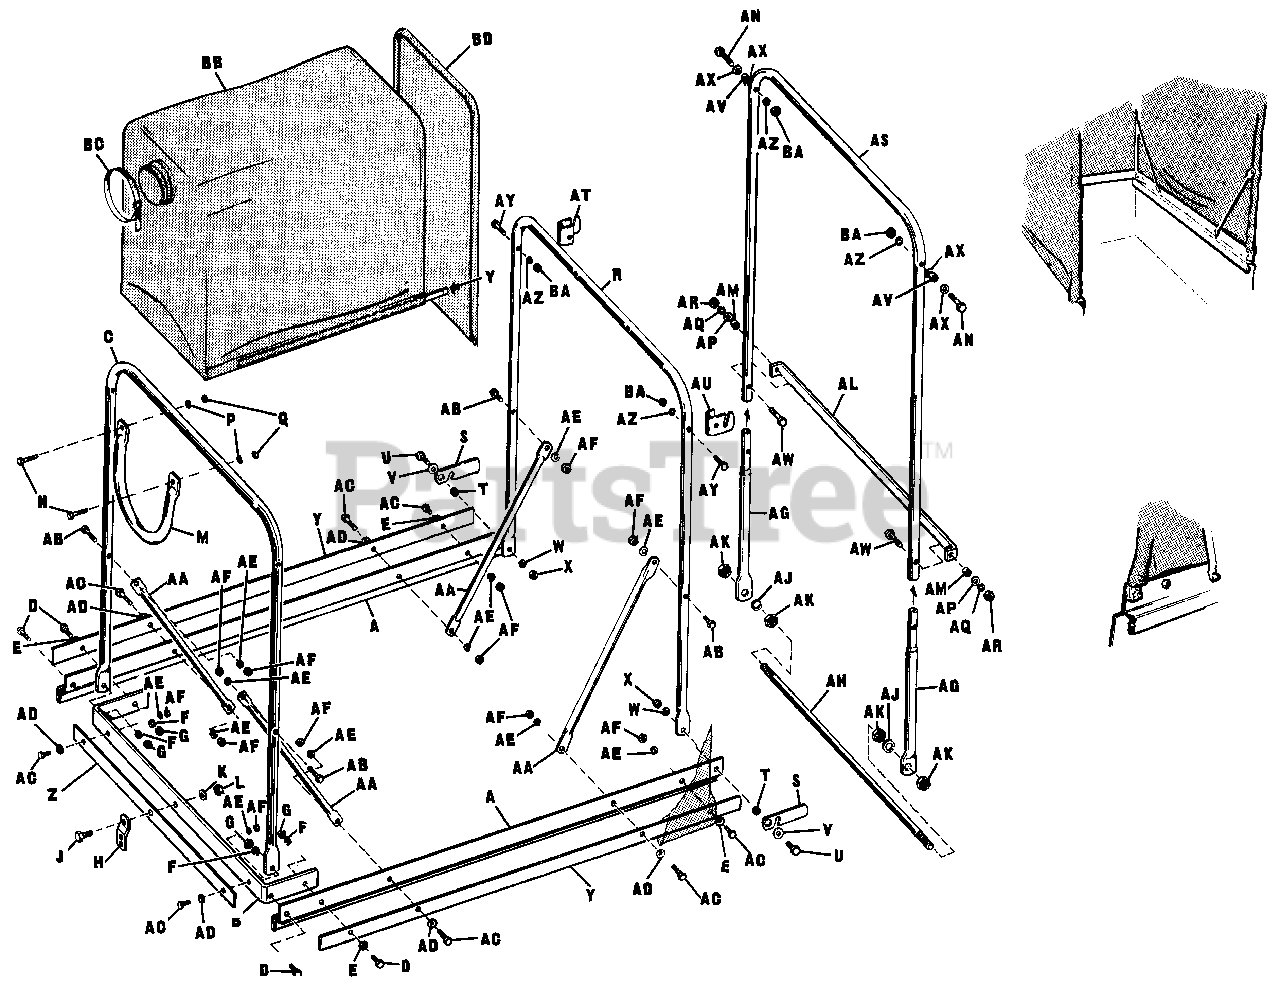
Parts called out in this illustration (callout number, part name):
A	"Z" Bar, Side
B	Front Bar
C	Front and Rear Upright
D	Hex Capscrew, 5/16"-18 x 1" lg.
E	Plain Washer, 5/16"
F	Lock Washer, 5/16"
G	Hex Nut, Full, 5/16"-18
J	Hex Capscrew, 3/8"-16 x 1" lg.
K	Plain Washer, 3/8"
L	Hex Lock Nut, Full, 3/8"-16
M	Hose Support
N	Hex Capscrew, 1/4"-20 x 1-1/4 lg.
P	Lock Washer, 1/4"
Q	Hex Nut, Full, 1/4"-20
R	Front and Rear Upright
S	Rear Door Latch
U	Hex Capscrew, 5/16"-18 x 7/8" lg.
V	Plain Washer, 5/16"
W	Lock Washer, 5/16"
X	Hex Nut, Full, 5/16"-18
Y	Hold Down Strip, Side
Z	Hold Down Strip, Front
AA	Cross Brace Tube
AB	Hex Capscrew, 1/4"-20 x 1-1/4" lg.
AC	Hex Capscrew, 1/4"-20 x 3/4" lg.
AD	Plain Washer, 1/4"
AE	Lock Washer, 1/4"
AF	Hex Nut, Full, 1/4"-20
AG	Tube, Rear Door
AH	Rod, Rear Door
AJ	Lock Washer, 1/2"
AK	Hex Nut, Full, 1/2"-13
AL	Bar, Rear Door
AN	Hex Capscrew, 1/4"-20 x 1-3/4" lg.
AP	Plain Washer, 1/4"
AQ	Lock Washer, 1/4"
AR	Hex Nut, Full, 1/4"-20
AS	Top Rear Door
AT	Catch, Door, R.H.
AU	Catch, Door, L.H.
AW	Hex Capscrew, 1/4"-20 x 1-3/4" lg.
AX	Plain Washer, 1/4"
AY	Hex Capscrew, 1/4"-20 x 1-1/4" lg.
AZ	Lock Washer, 1/4"
BA	Hex Nut, Full, 1/4"-20
BC	Hose Strap
